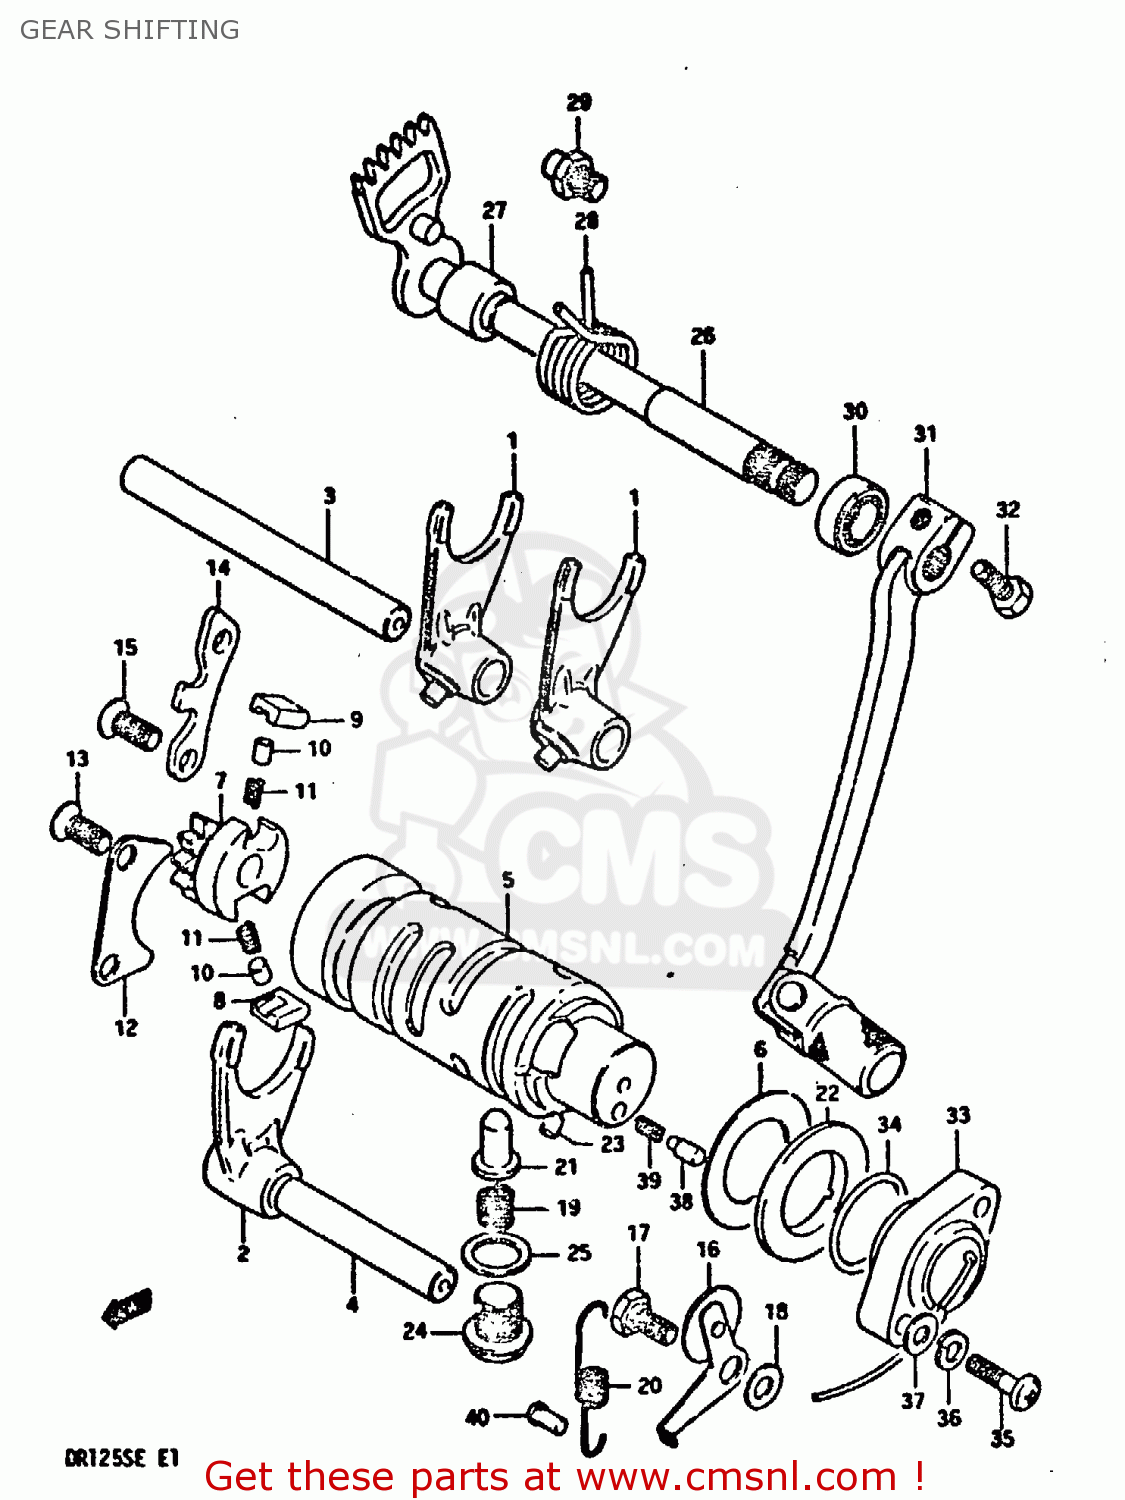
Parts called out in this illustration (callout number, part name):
1	FORK,GEAR SHIFT NO.1
2	FORK,GEAR SHIFT NO.3
3	SHAFT,GEAR SHIFT FORK
4	SHAFT,GEAR SHIFT FORK
5	CAM,GEAR SHIFT
6	WASHER,THRUST
7	SHIFTER,GEAR SHIFT CAM
8	PAWL,GEAR SHIFT NO.1
9	PAWL,GEAR SHIFT NO.2
10	PIN(5X8)
11	SPRING
13	SCREW
14	GUIDE,GEAR SHIFT CAM
15	SCREW
16	STOPPER,GEAR SHIFTING
17	BOLT
18	WASHER
19	SPRING
20	SPRING
21	STOPPER,GEAR SHIFT CAM NO.2
22	PLATE,GEAR SHIFT CAM STOPPER
23	PIN 4X6
24	PLUG (14X12)
25	GASKET(14X19.2X2) (NAS)
26	SHAFT,GEAR SHIFT
27	SPACER(12X20X15.3)
28	SPRING
29	STOPPER,GEAR SHIFT CAM
30	OIL SEAL
31	LEVER ASSY, GEAR SHIFTING
32	BOLT
33	TERMINAL BASE,NEUTRAL SWITCH
34	O-RING (D:2.4 ID:26.2)
35	SCREW 5X20
36	LOCK WASHER
37	WASHER
38	PIN(5X15.5)
39	SPRING
40	RIVET
